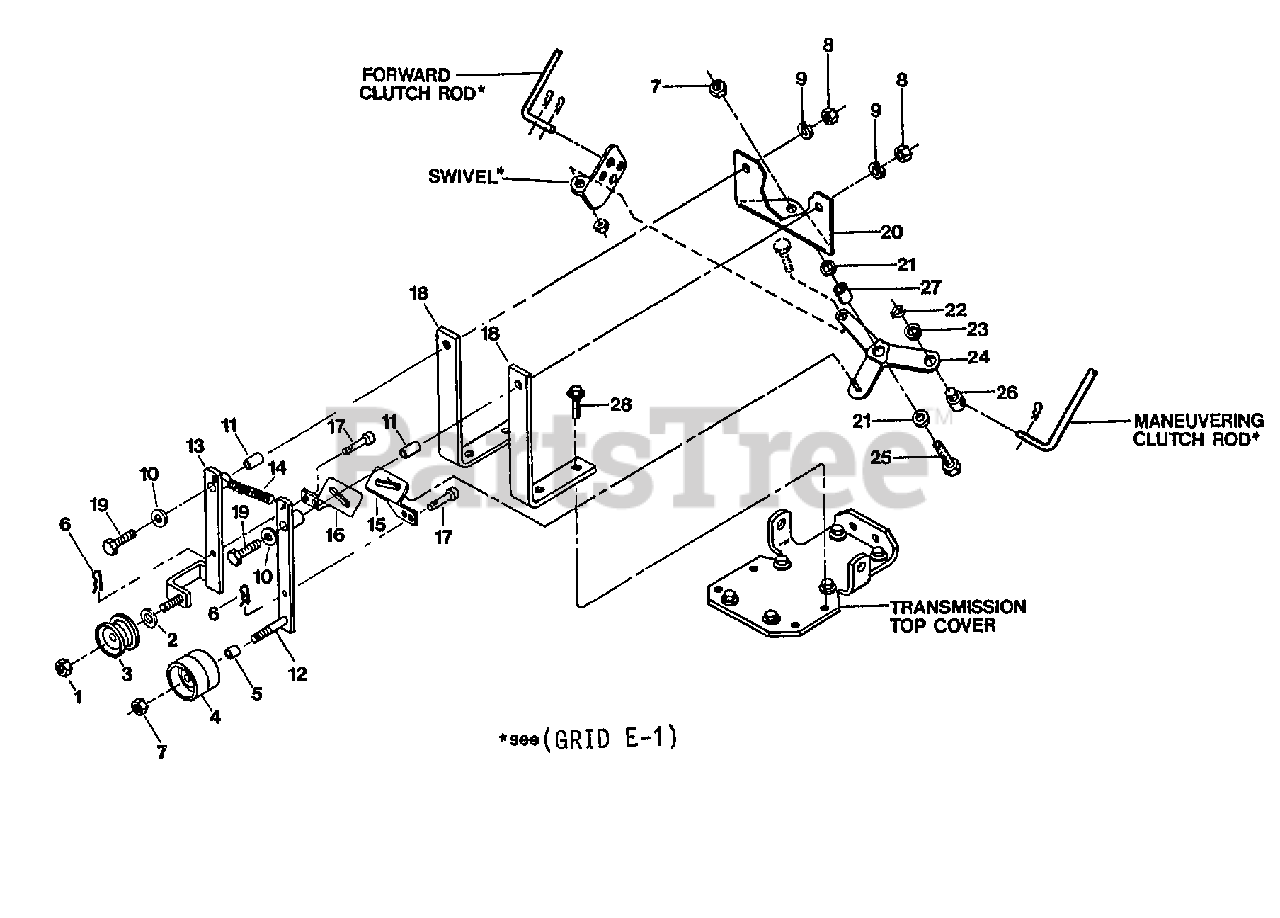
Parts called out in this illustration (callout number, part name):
1	NUT-LOCK 3/8-16 NYLON ZP
2	BUSHING-.54X.38X.08
3	IDLER-REV
3	PULLEY-IDLER REVERSE
4	PULLEY-FWD IDLER
5	BUSHING-.5X.375X.3
6	PIN-CLIP .08
7	NUT-H/LK 3/8-16
8	NUT-HEX 5/16-18 ZP
9	WASHER-LK .312 ZP
10	WASHER-#.75X.32X.09 ZP
11	BUSHING-.438X.323X.712
12	ARM-IDLER FWD PNT
13	IDLER-REV
13	ARM-IDLER REV RED
14	SPRING-.436 X 3.25
15	LINK-FWD
17	PIN-CLEVIS .375X.719 ZP
18	MOUNT BAR-PNT (20691)
19	SCR-HH 5/16-18X2.25 G5ZP
20	SHIFT BASE-OPC PNT
21	SPACER-.88X.385X.09 ZP
22	RING-KLIP .500 ZINC
23	WASHER-#.88X.51X.063 ZP
24	BELLCRANK-OPC PNT
25	SCR-HH 3/8-16X1.25
26	PIVOT-ROD
27	BUSHING-.5X.38X.4
28	SCR-HFLK 5/16-18X1.00 ZP
